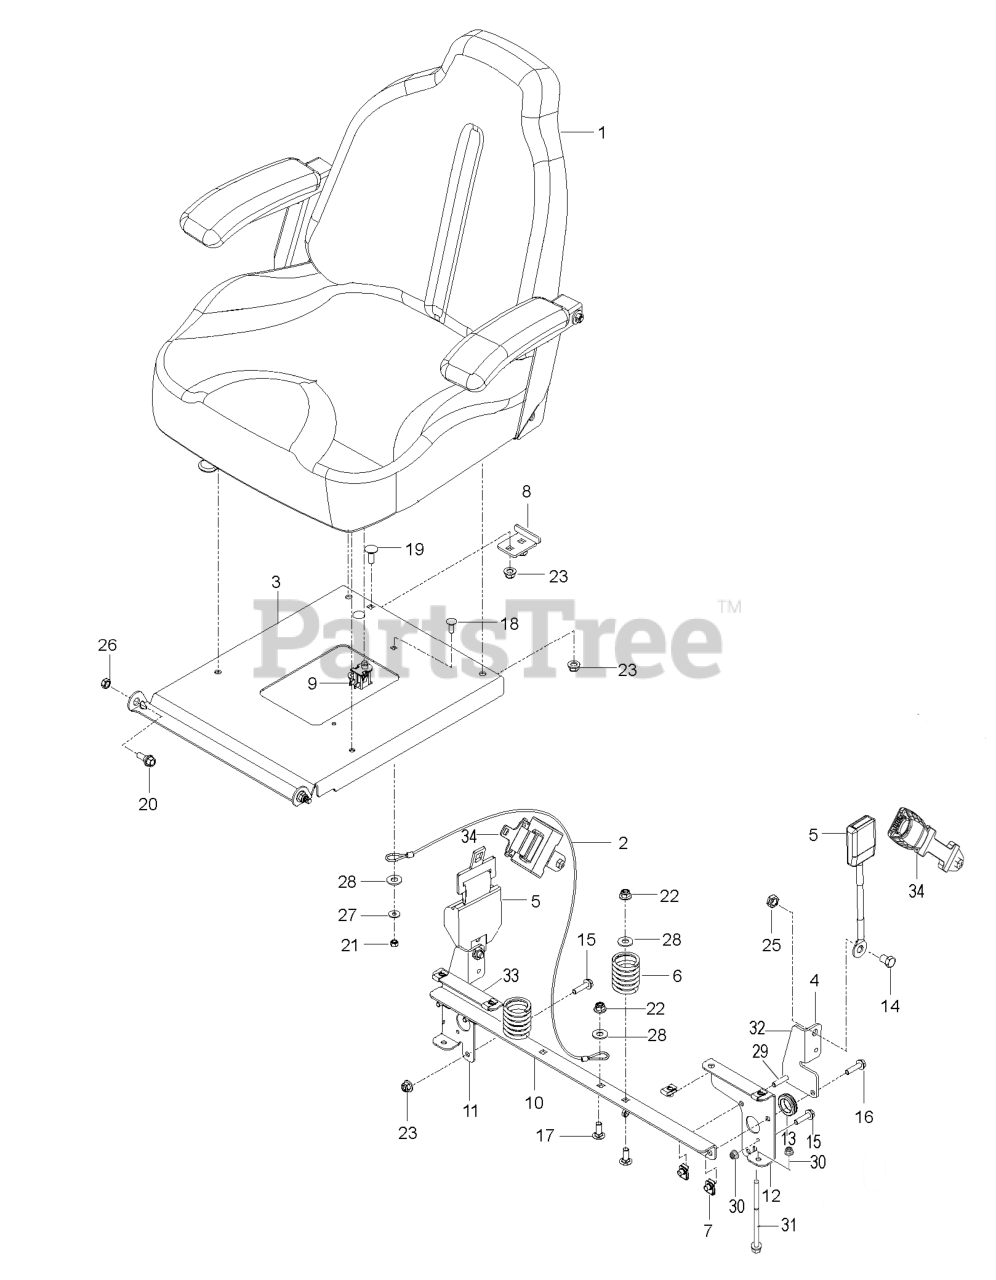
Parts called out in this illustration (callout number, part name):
1	SEAT.ASM.907.TRACK.W/O.BELT
2	SEAT LANYARD
3	SUPPORT.SEAT.ORANGE
4	MOUNT.SEAT.BELT.BLACK
5	SEAT BELT, RETRACTABLE
6	SPRING.COMPRESSION.SEAT.BLACK
6	Springs
7	U-CLIP 5/16-18 NUT RETAINER
8	STOP, SEAT - BLACK
9	SWITCH.SNAPMOUNT.NC
10	SUPPORT.SEAT. BLK
10	Brackets
11	SUPPORT.RT.BLK
12	SUPPORT.LT.BLK
13	RUBBER GROMMET
14	HCS 7/16-20 X .75 GD 5
16	HHFS 5/16-18 X 1.25 TPBLT GD 5
17	BOLT D
17	Bolts
18	BOLT
19	RHSNB 5/16-18 X 3/4 GR5 BLK ZN
20	SB 5/16-18 HEX HD GD5, BLK ZN
21	NUT HEXAGON 1/4-20 ST ZPB
22	GSPW Nuts
23	NUT HEXAGON FLANGE 5/16-18 ST
25	NUT HEX 7/16F LOCK RP
26	NUT.71038.31-18.HEX.NYLOCK
28	GSPW Washers
30	NUT HEXAGON FLANGE 5/16-18 ST
31	Bolts
31	BOLT.HEX.FLNG.5/16-18X3.75
32	SUPPORT.RT.BLK
33	SUPPORT.RT.BLK
34	SEAT.BELT
